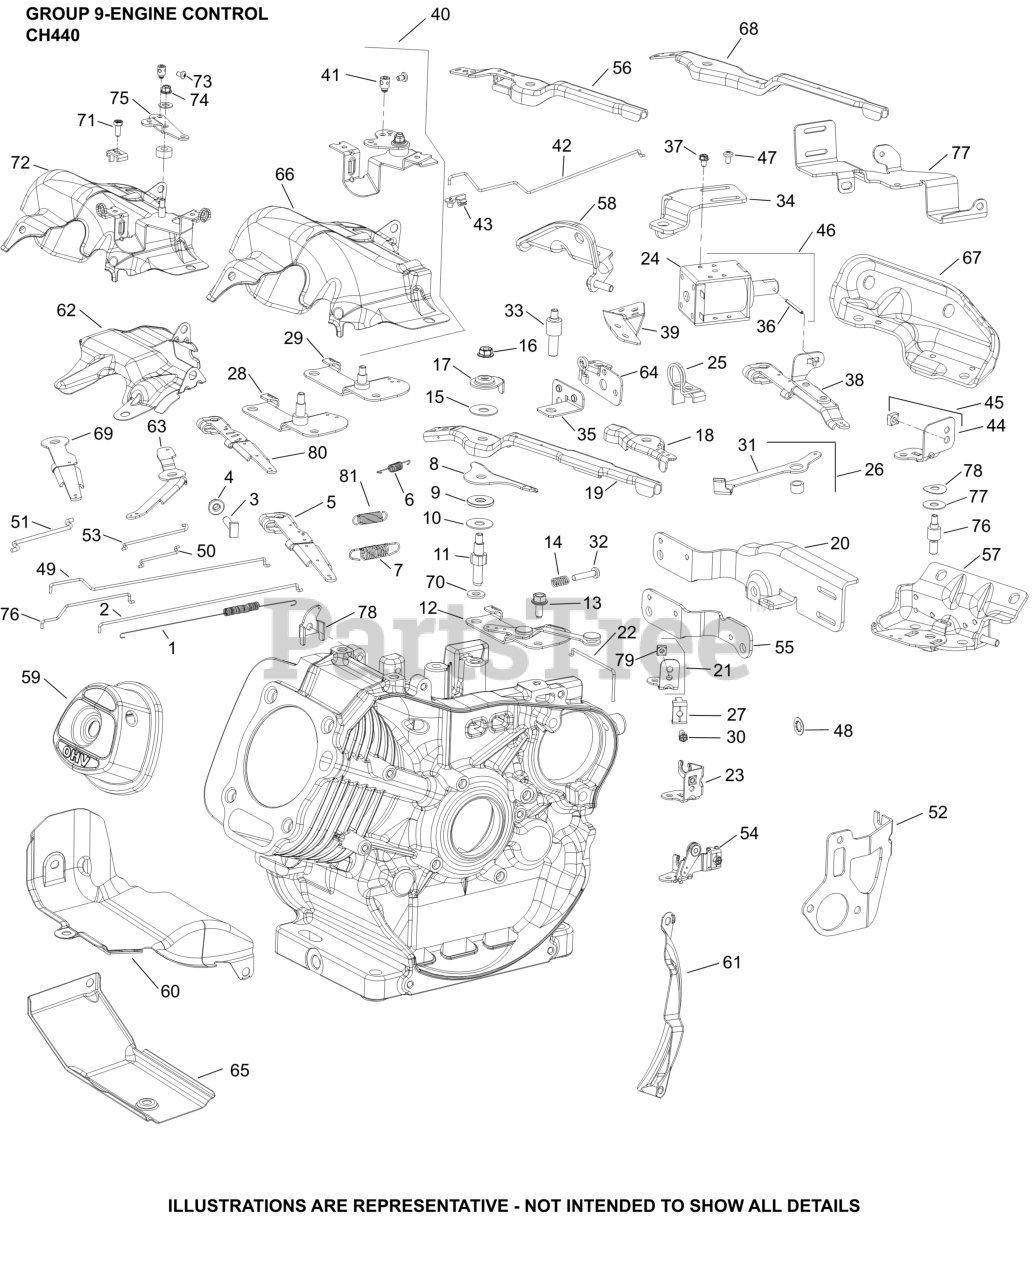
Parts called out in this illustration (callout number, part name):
1	SPRING, LINKAGE
2	LINKAGE, GOVERNOR
3	SCREW, RECTANGLE HEAD (M6)
4	NUT, HEX FLANGE (M6) - USE 14 100 16-S
5	LEVER, GOVERNOR
7	SPRING, GOVERNOR
8	LEVER, FIXED SPEED
14	SPRING, COMPRESSION
16	NUT, HEX FLANGE LOCK (M6)
27	CLAMP, CABLE
32	SCREW, SPEED ADJUSTING
32	SCREW SPEED ADJUSTING
33	STUD, CONTROL LEVER
34	BRACKET, IDLE DOWN SOLENOID
35	BRACKET, CONTROL
38	LEVER ASSEMBLY, GOV. IDLE PULL DOWN
44	BRACKET, REMOTE CHOKE
45	BRACKET REMOTE, CHOKE ASSEMBLY
46	KIT, SOLENOID IDLE
47	SCREW, SET HEX FLANGE HEAD
